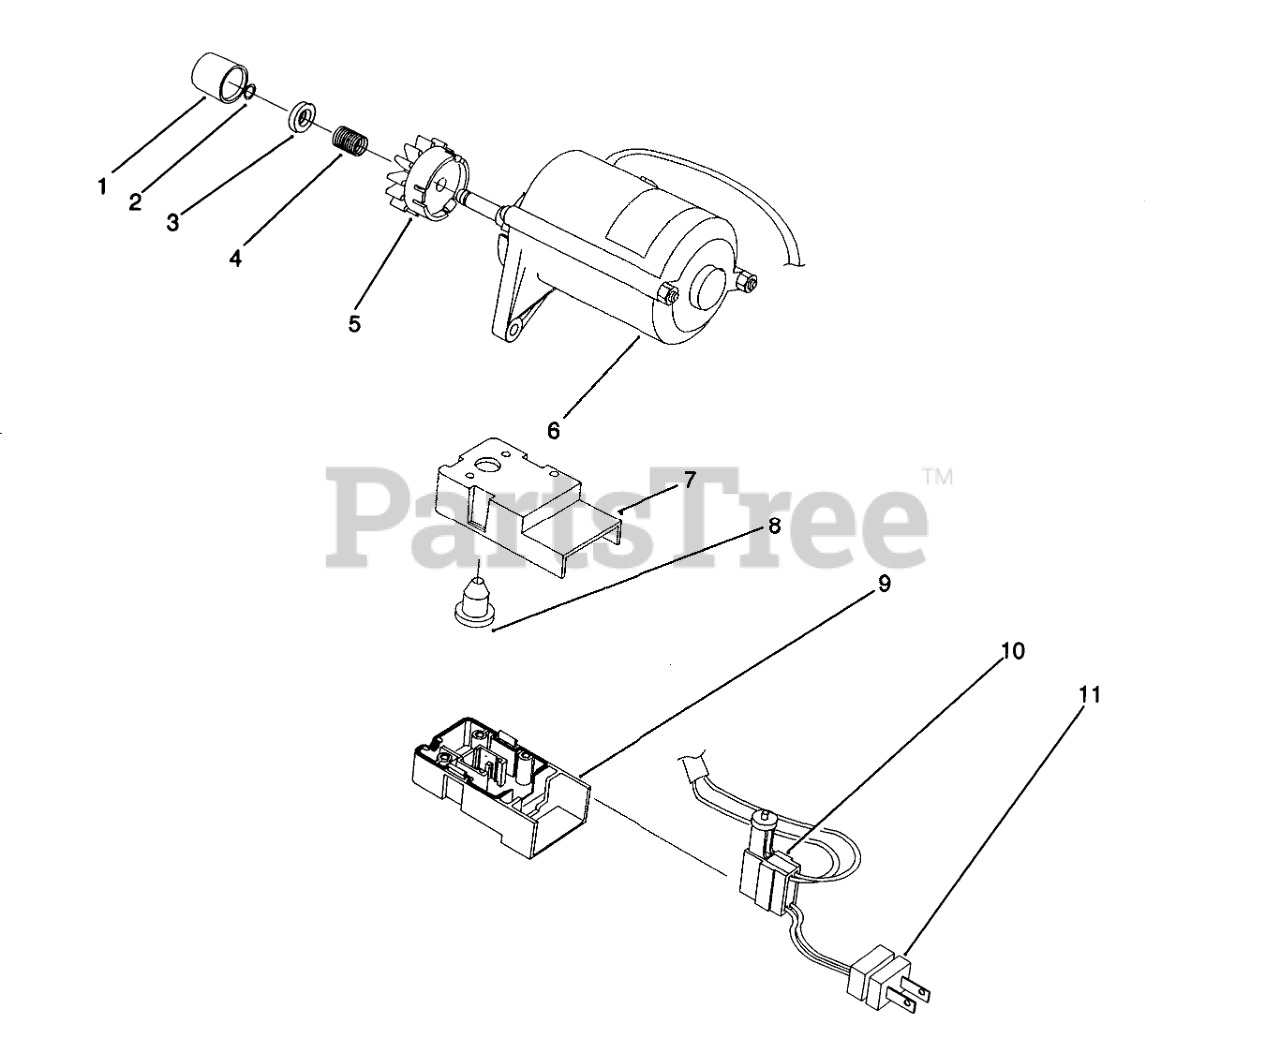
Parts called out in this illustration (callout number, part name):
1	CAP-PINION
2	RING-LOCK
3	PINION STOP
4	SPRING
5	PINION ASM
6	ASM-Switch Housing
7	Cap-Switch Housing
8	BOOT-SWITCH
9	OBS BASE X
10	SWITCH-STARTER
11	Plug
